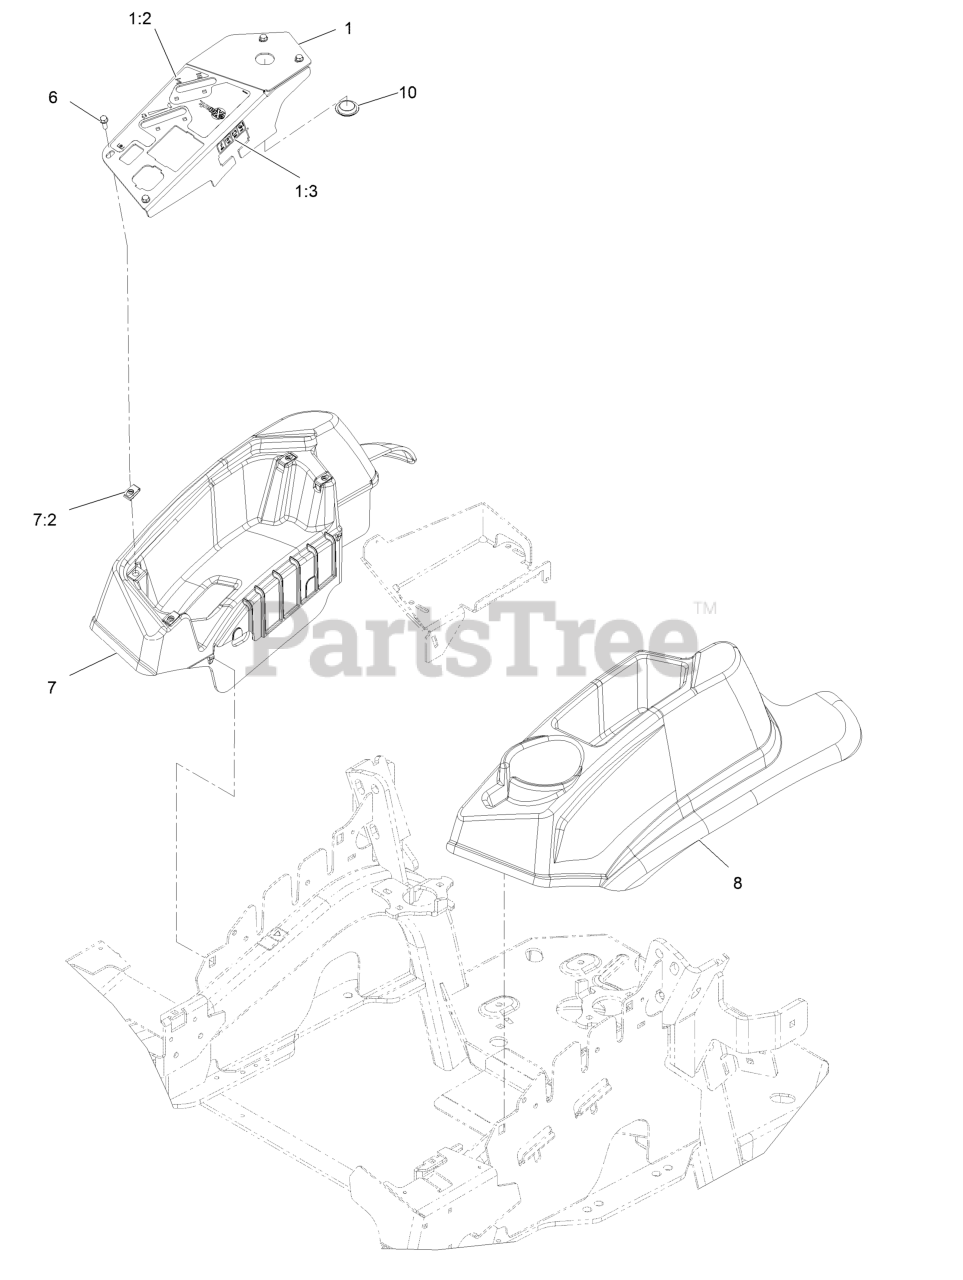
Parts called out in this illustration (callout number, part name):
1	Console,Panel W/Decal
1:2	Decal-Control Panel Non-Efi
1:3	Decal-Fuses
6	Screw-Machine 1/4-20 X 3/4
7	Console,RH As ASM
7:2	Nut-Retainer-Panel 1/4-20
8	Console, LH As
10	Plug-Plastic
